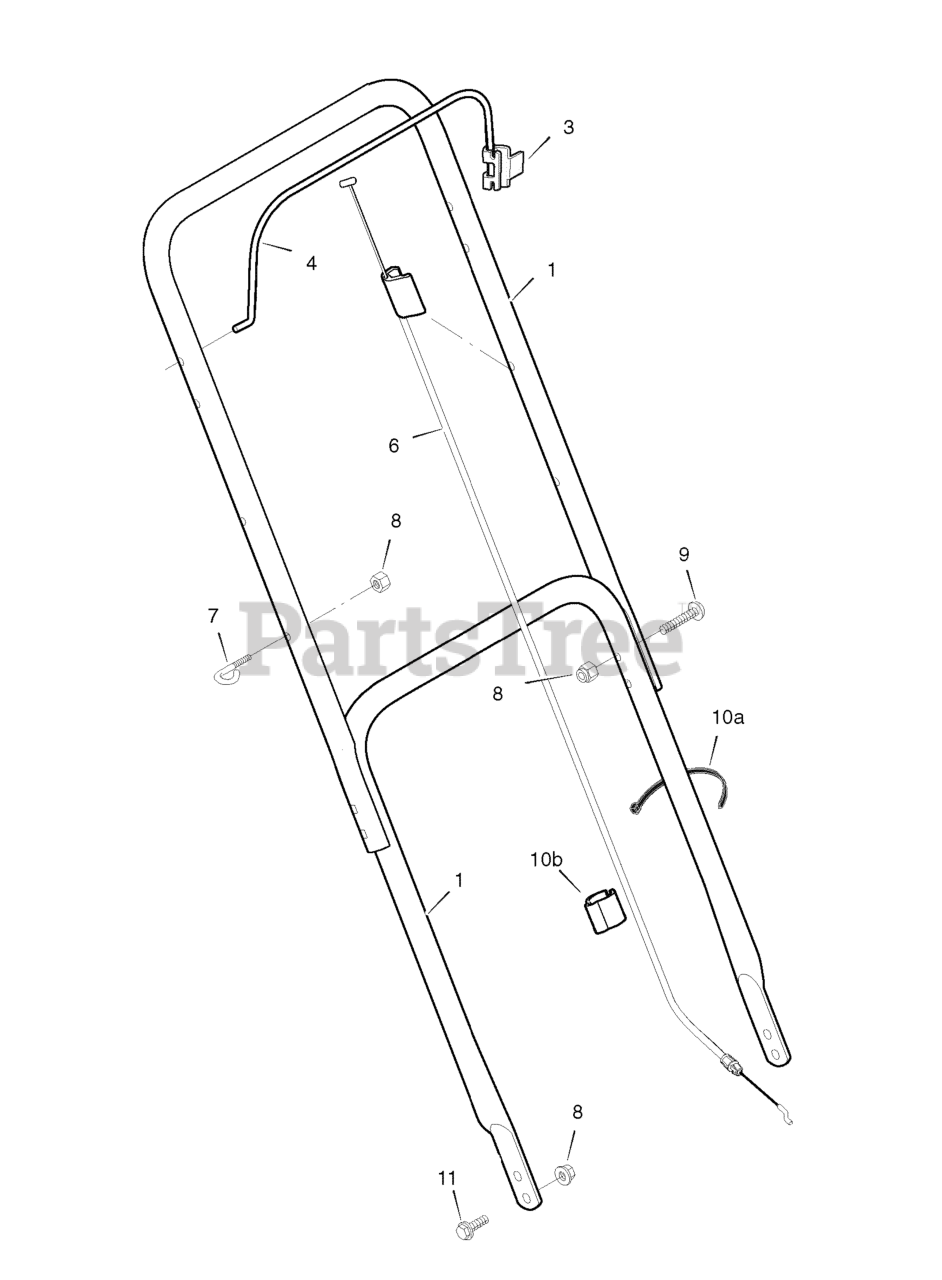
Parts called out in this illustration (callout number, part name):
3	BRACKET, Stop Lever
4	LEVER, Stop
6	CABLE, Stop
7	GUIDE, Rope
8	NUT, Hex Nylock, 1/4-20
9	BOLT, Carriage, Short Neck, 1/4-20 x 1-3/8
11	BOLT, Carriage, Short Neck, 1/4-20 x 3/4, G5
